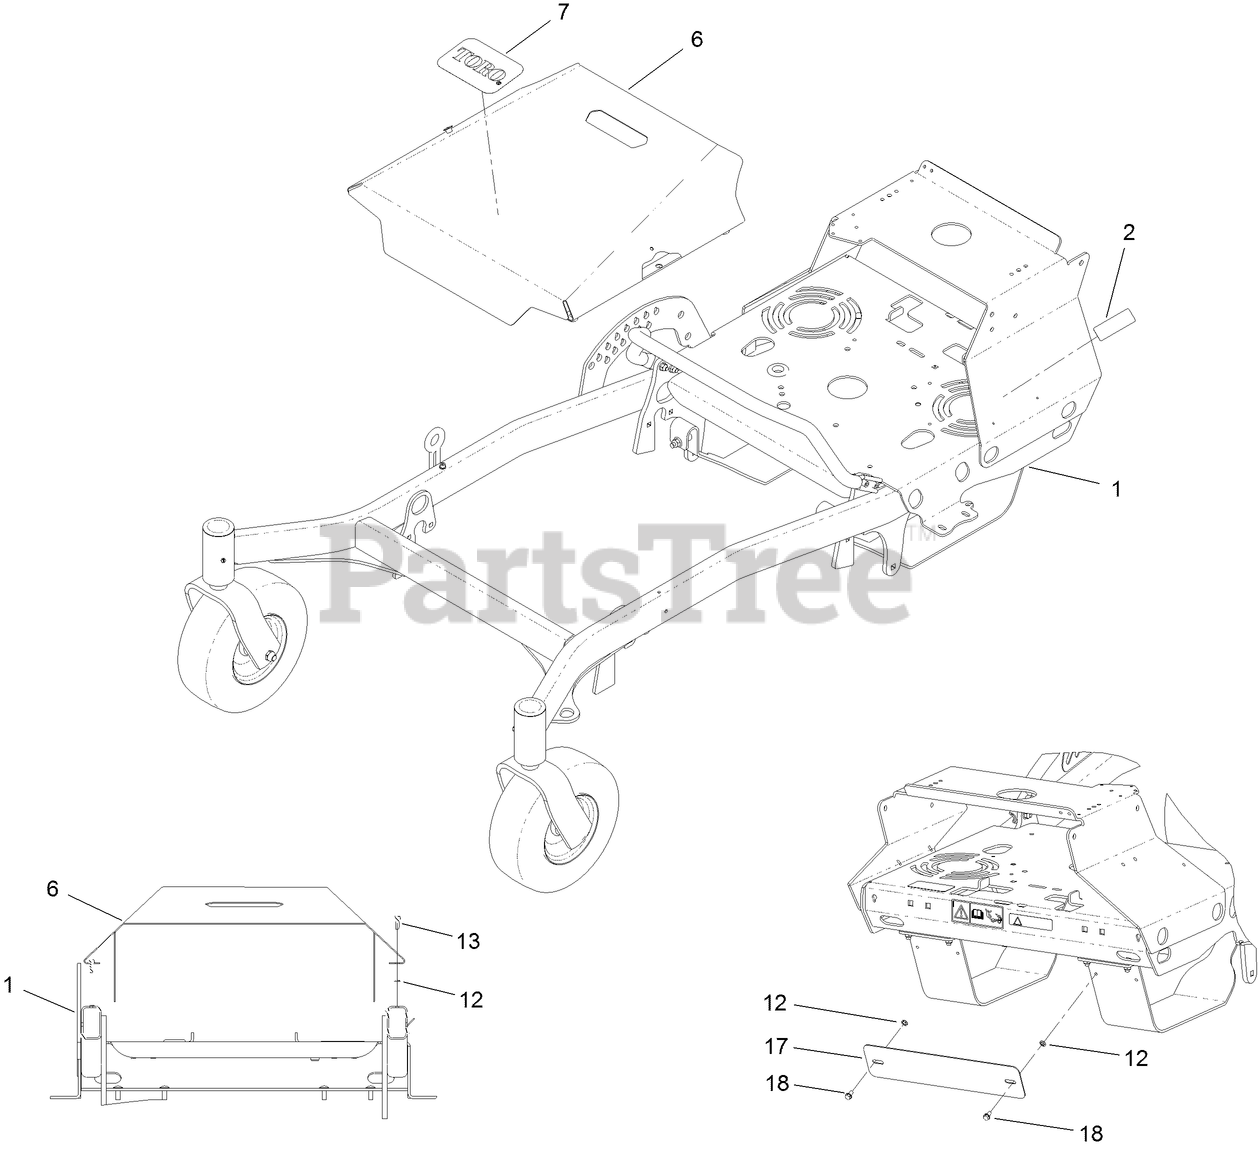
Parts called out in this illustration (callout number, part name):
1	FRAME ASSEMBLY
2	DECAL-EMISSIONS, EXPORT
6	COVER-DECK,WIDE
7	DECAL
12	NUT-RETAINING
13	SCREW-HWHTF
17	PLATE-GUARD, INTL [BLACK]
18	SCREW-HWH
